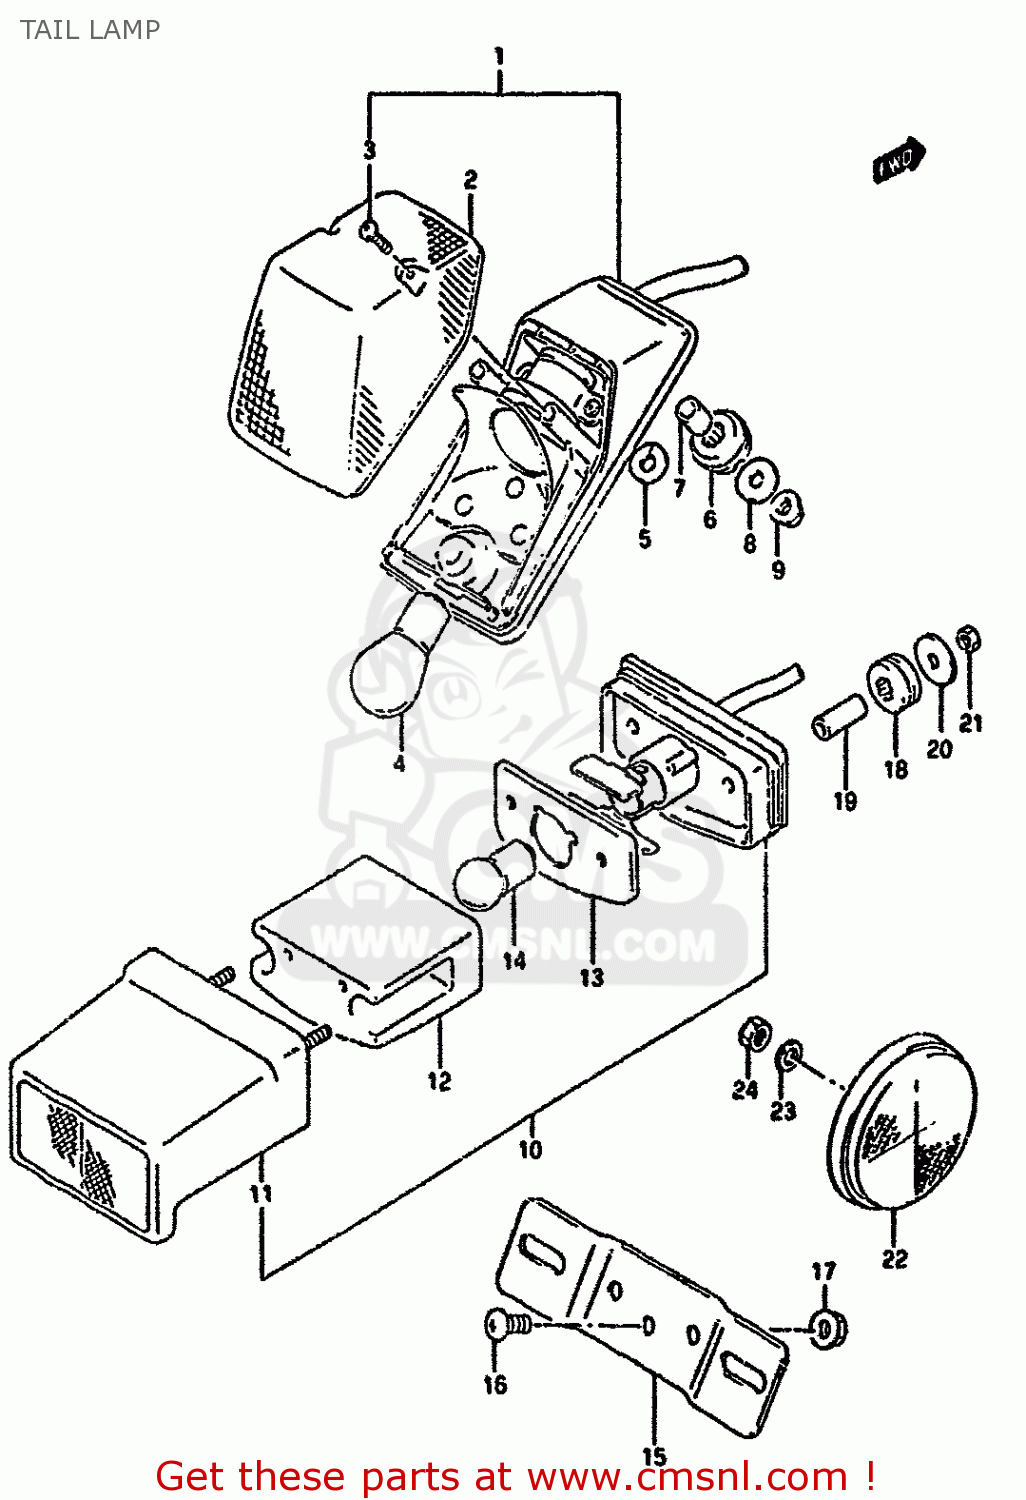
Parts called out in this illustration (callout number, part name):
1	LAMP ASSY,TAIL
2	LENS
3	SCREW
4	BULB(12V21/5W)
5	GASKET (NAS)
6	CUSHION
7	SPACER(6.4X9.2X12)
8	WASHER,COVER,FRONT
9	NUT
10	LAMP ASSY,LICENSE
11	REFLECTOR/COVER
12	LENS
13	GASKET,LICENSE LAMP (NAS)
14	BULB(12V5W,BF150-40160A)
15	PLATE,RR LICENSE
16	SCREW
17	NUT
18	CUSHION
19	SPACER (5.5X9.5X19.50)
20	WASHER(5.5X20X1.2)
21	NUT
22	REFLECTOR,REFLEX FR
23	WASHER,LOCK
24	NUT
